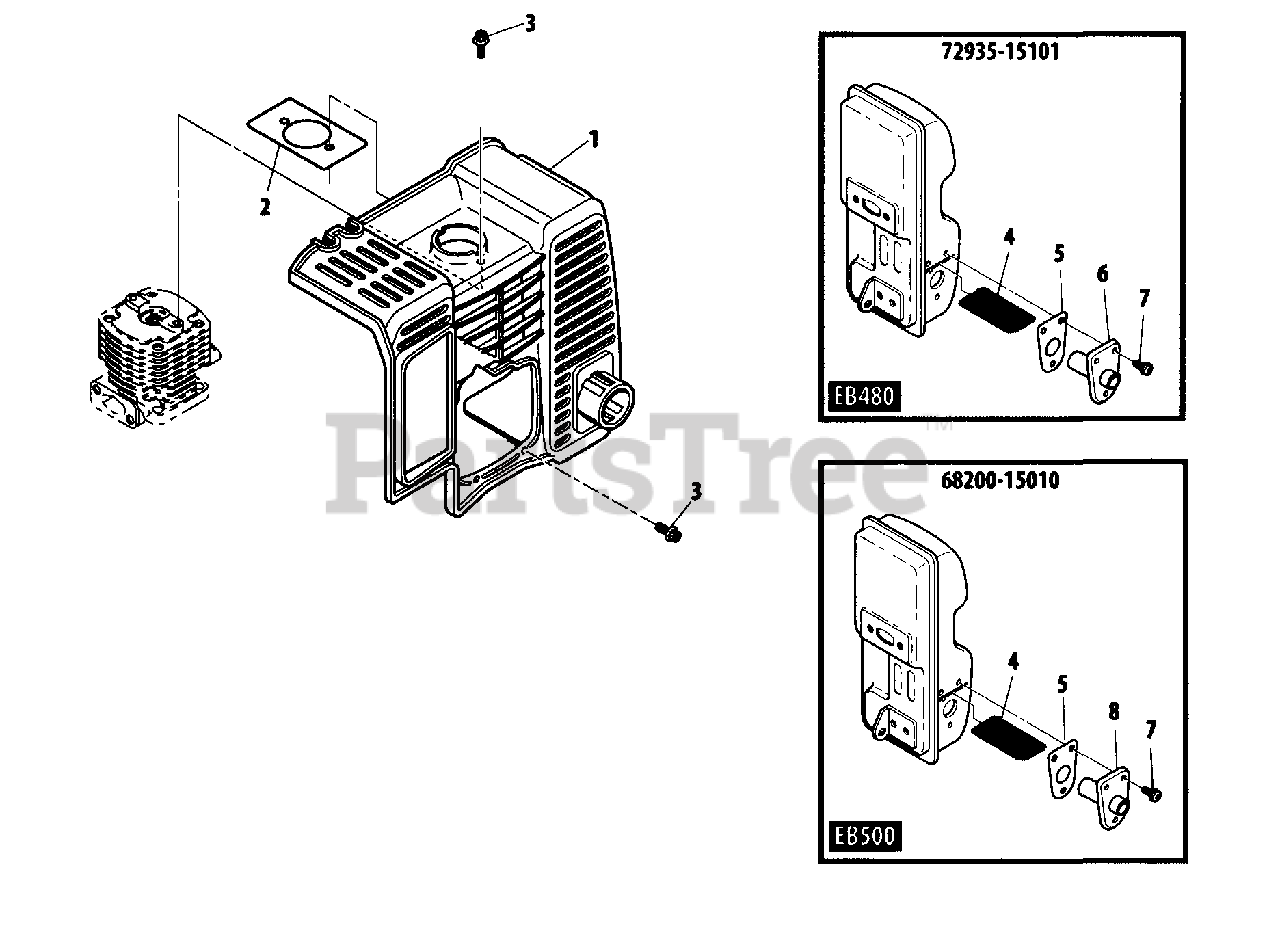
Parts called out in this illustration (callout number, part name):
1	ENGINE COVER PR171
2	GASKET
3	BOLT, ADHESIVE M5×16
4	SCREEN, SPARK ARRESTER
5	GASKET, EXHAUST
6	PIPE, TAIL
7	SCREW M4×12
8	GUIDE, EXHAUST
68200-15010	MUFFLER ASSY
72935-15101	MUFFLER ASSY
